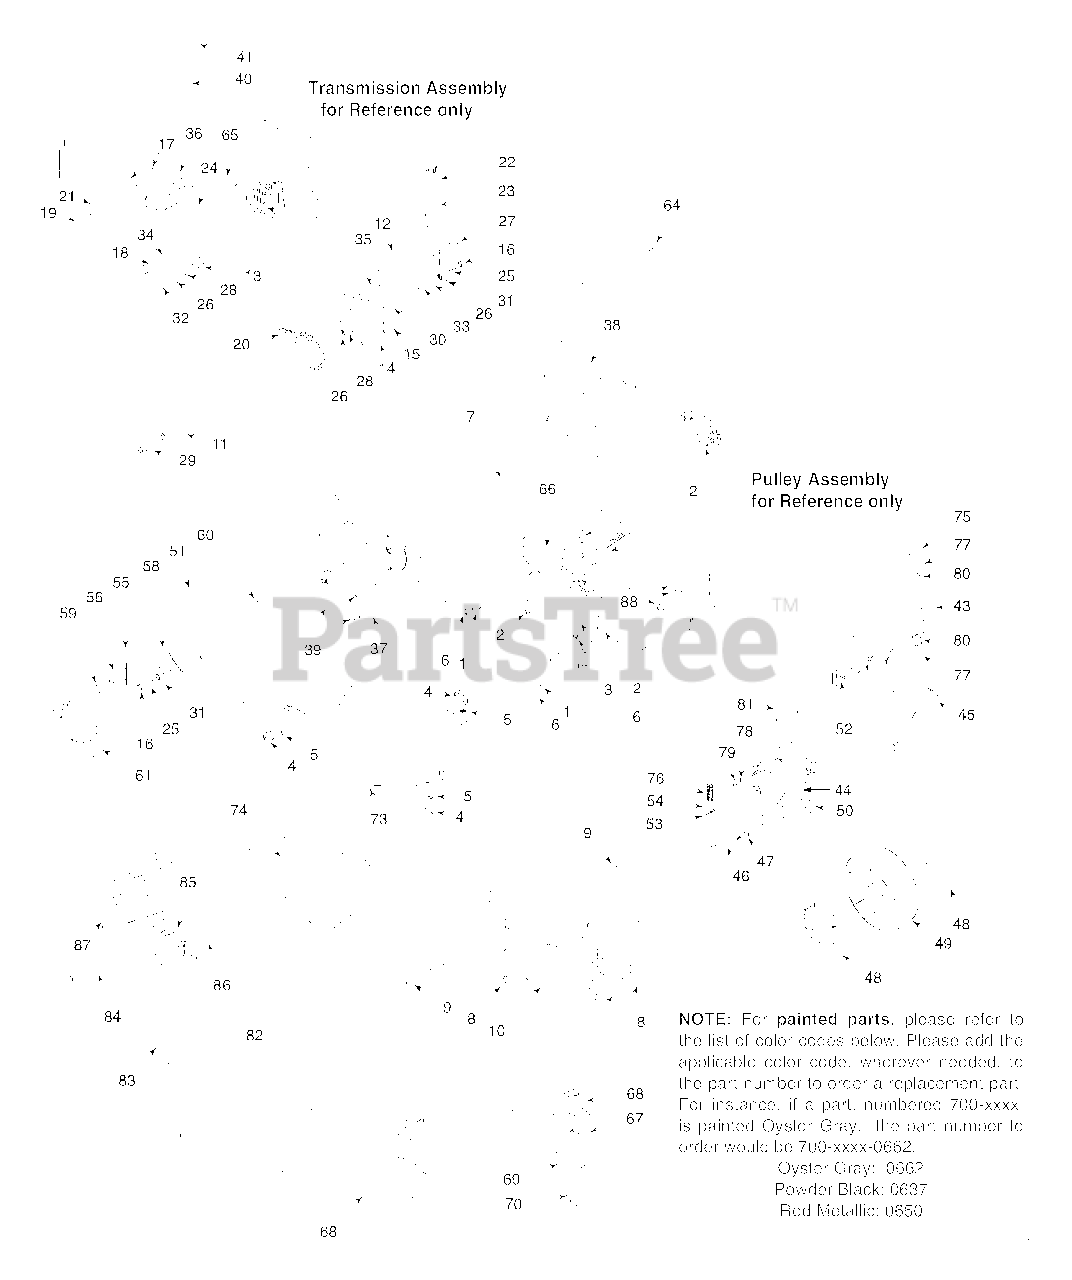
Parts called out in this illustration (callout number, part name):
1	Scr. Carr. 1/4-20 x .62
2	Scr. TT:3/8-18:1.00
3	Carriage Scr. 1/4-20 x .750
4	Wing Nut 1/4-20
5	Nut, Push .25 I.D. x .50 O.D.
6	Wash. Fl. .334 I.D.x .62 x.03
8	Scr. TT. 1/4-20 x .375
9	Scr. HL. 1/2-14 x .750
10	Baffle
11	Rear Axle Assembly
16	Cap Screw HH 1/4-20 x .620
17	Scr. AB 1/4-20x.625
18	Scr. 3/8 116 x .25
19	Clevis Pin .50 Dia. x 4.82 Lg.
20	Chain-Endls. #48 .500P x 24L
21	Cotter Pin .125 O.D. x .75
24	Torsion Spring
25	Bell Wash. .285 x .75 x .082
26	Fl. Wash..508 I.D. 1.000 x.020
27	Nut Shld. .825 Dia. x .165 Lg.
28	Hx.Flg. Brg..506 I.D. x .590 L.
29	Hx.Flg. Brg. .506 I.D. x.715 L.
30	Hx. Slv. Brg..504 I.D. x .830 L.
31	Wheel Rachet
32	Spacer .550 I.D. x .750 O.D.
33	Spacer .51 .D. x .70 O.D. x 38 L.
34	Spacer .385 x .624 x .700
35	Shld. Spacer .385 I.D. X .715 Lg.
40	Trail Shield
41	Trail Shield Wire
46	Caster Axle .374 Dia x 2.50"
48	Hub Cap, Gray w/ Hole
49	Wheel 7 x 2 Link
50	Wing Nut 1/4-20
51	Wheel 9 x 2 Link
52	Lock Nut 5/15-18
53	Cotter Pin .072 x .12 Lg.
54	Fl. Wash. .330 x .830 x .060
55	Spring, Ratchet, Plastic
56	Pawl - L.H.
58	Ratchet Pawl Plate
59	Scr. Shld. .340 x .285
60	Top Lock Tab Weld Nut 1/4-20
61	Hubcap, Gray w/o hole
65	Hex Scr. 5/16-18
66	Belt, 3/8" x 39.24"
67	21" Mulching Blade
68	Blade Adapter
69	Blade Bell Support
70	Hex Bolt 3/8-24x2.5" Lg.
73	Side Discharge Chute
74	Mulch Cover
76	Compression Spring
77	Fl. Wash. .5/8 I.D. x 1" O.D.
78	Fl. Wash. .203 x .403 x .040
79	Fitting - Grease
80	Flange Bearing
82	Chute Ass'y
83	Discharge Chute
85	Torsion Spring
87	Chute Door
88	Carr. Bolt 5/16-18 x.62
